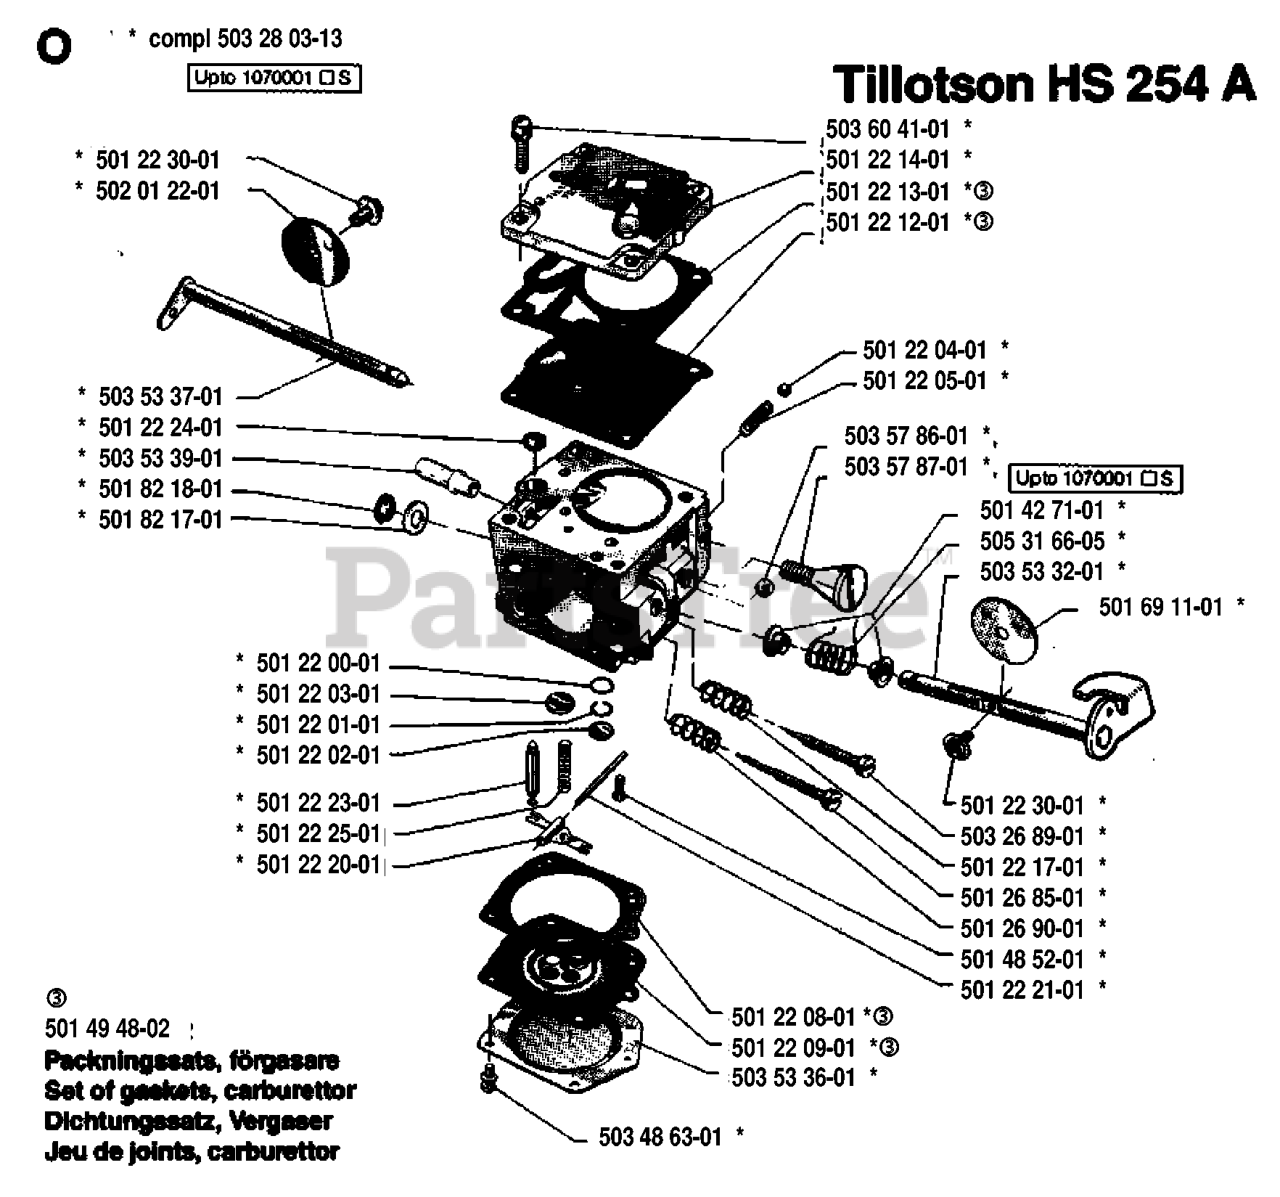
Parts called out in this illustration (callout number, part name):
2	SPRING BRAKE
3	PULLEY, TRANSAXLE
8	ROD SHIFT FENDER
9	CLUTCH.ELECT.EVX.
10	PIN COTTER
15	BOLT HEX 5/16-18 GR 5
16	NUT.71038.31-18.HEX.NYLOCK
19	NUT
20	BOLT HEX
21	KNOB.DELUXE.(PISTOL.GRIP).BLAC
22	ROD BRAKE HYDRO
23	BRACKET, ASM CLUTCH MTG
24	NUT
25	SPRING ROD LT
26	WASHER
27	COTTER PIN
28	ROD BRAKE PARK LT
29	PLUNGER CAP
30	BRACKET TRANSAXLE
31	KEEPER BELT LH
32	BOLT
33	RP BOLT 5/16-18 X3/4 ZN/YEL GR
34	SHAFT, FOOT PEDAL
35	BEARING.NYLON
37	DRIVE PIN
38	PULLEY.IDLER.FLAT
41	KEEPER, BELT IDLER
42	WASHER
47	IDLER PULLEY
48	BELLCRANK ASSEMBLY
49	RETAIN BELT
50	BOLT
52	LOCKNUT
53	LINK, CLUTCH LT
55	SPRING, RETURN LT
57	DRIVE BELT, LTH & YTH TRACTORS
59	KEEPER CENTER SPAN
61	SCREW
62	COVER, PEDAL (1 2)
63	PULLEY, CLUTCH ELECT EVX
65	LOCKWASHER
66	KEEPER BELT ENGINE
71	STRAP LH TORQUE
73	STRAP TORQUE RH HYDRO
74	SPACER SPLIT
77	SQUARE KEY
81	SHAFT ASSY
82	SPRING,TORSION
83	WASHER
84	ROD.TIE.BALL.4.75
86	BUSHING.STEERING.ROD LTB-WSL
89	CONSOLE SHIFT
90	NUT.PUSH.3/16
91	BOLT.FIN HEX 5/16-18UNC X2 1/4
92	HEX BOLT
93	LINE FUEL HYD 4"
94	FAN 7" HYDRO
95	CONTROL ARM, BYPASS HYDRO
96	RETAINER M
97	KEEPER BELT RH
100	WASHER M
103	NUT.HEX.1/2-20
104	CONTROL ARM
106	BOLT.5/16-18X1-1/4 FULL.THREAD
114	Washer 11/32 x 3/4 x 14 Gauge
118	SPACER BELLCRANK
121	NYLINER CLUTCHING
